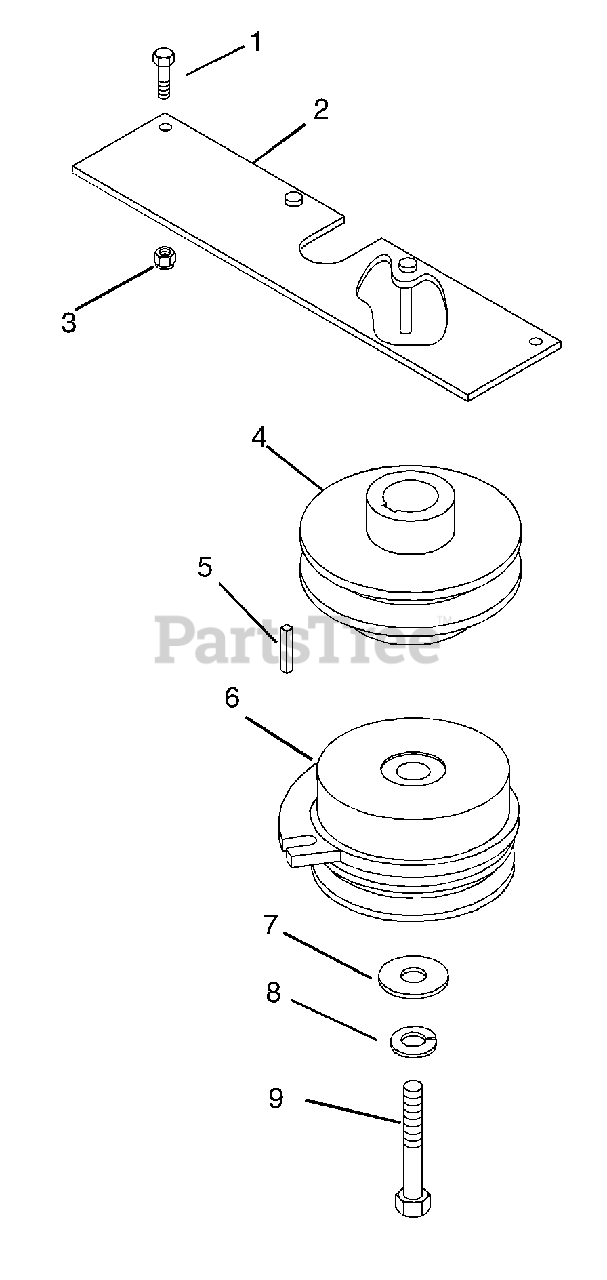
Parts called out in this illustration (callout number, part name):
1	Bolt-Hex .31-18 x .75 Grade 5
2	Anchor, Clutch
3	Nut-Locking-Nylon .312-18
5	Key-Square .25 x 1.5 x .25
6	Clutch-Electric
7	Washer-Flat-steel .469 x 2.00 x .25
8	Washer-Locking .44 x .109
9	Bolt-Hex .44-20 x 3.00 Grade 5
